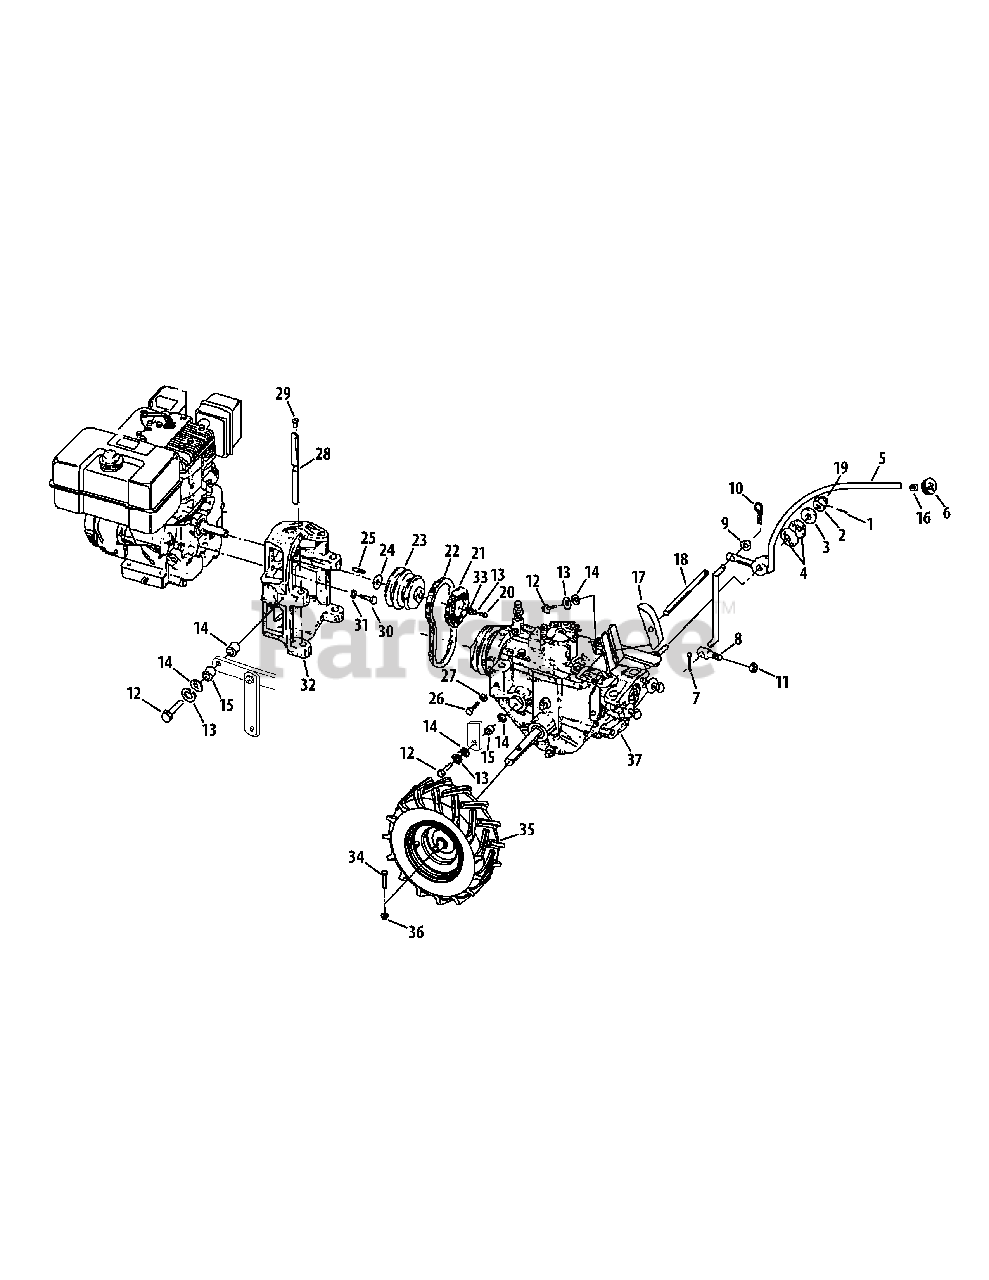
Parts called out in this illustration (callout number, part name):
1	Spring Pin, 1/8"
2	Flat Washer, 510 x 10 x 125
3	Shoulder Washer, 125 x 50 x 25
4	Disc Spring Washer
5	Wheel Speed Shift Lever
7	Cotter Pin, 3/32" x 1"
9	Flat Washer, 344 x 688 x 065
10	Hair Pin Cotter
11	Hex Locknut, 5/16"-18
12	Hex Head Screw, 3/8"-16 x 1"
13	Lockwasher, 3/8"
14	Flat Washer, 406 x 810 x 051
15	Bushing Spacer, 5 x 375 x 3
16	Retaining Ring
17	Belt Adjustment, 3-7/8"
18	Belt Adjustment Rod
19	Hex Nut, 1/2"-20
20	Hex Head Screw, 3/8"-24 x 175
21	Reverse Disc
22	Forward Drive Belt
23	Engine Power Take-off Pulley
24	Flat Washer, 766 x 10 x 031
24	Flat Washer, 766 x 10 x 062
25	Engine Pulley Key, 3/16"x 2-1/2"
26	Hex Head Screw, 5/16"-18 x 1"
27	Hex Nut, 5/16"-18
28	Engine Mounting Bar
29	Thread Protector Plug
30	Hex Head Screw, 5/16"-24 x 1125
31	Lockwasher, 5/16"
33	Flat Washer, 406 x 10 x 105
34	Hex Screw, 1/4"-20 x 1-1/2"
35	Wheel Assembly, 16 x 46 x 8"
35	Tire, 162 x 46
36	Hex Flange Nut, 1/4"-20
37	Clutch Bracket
